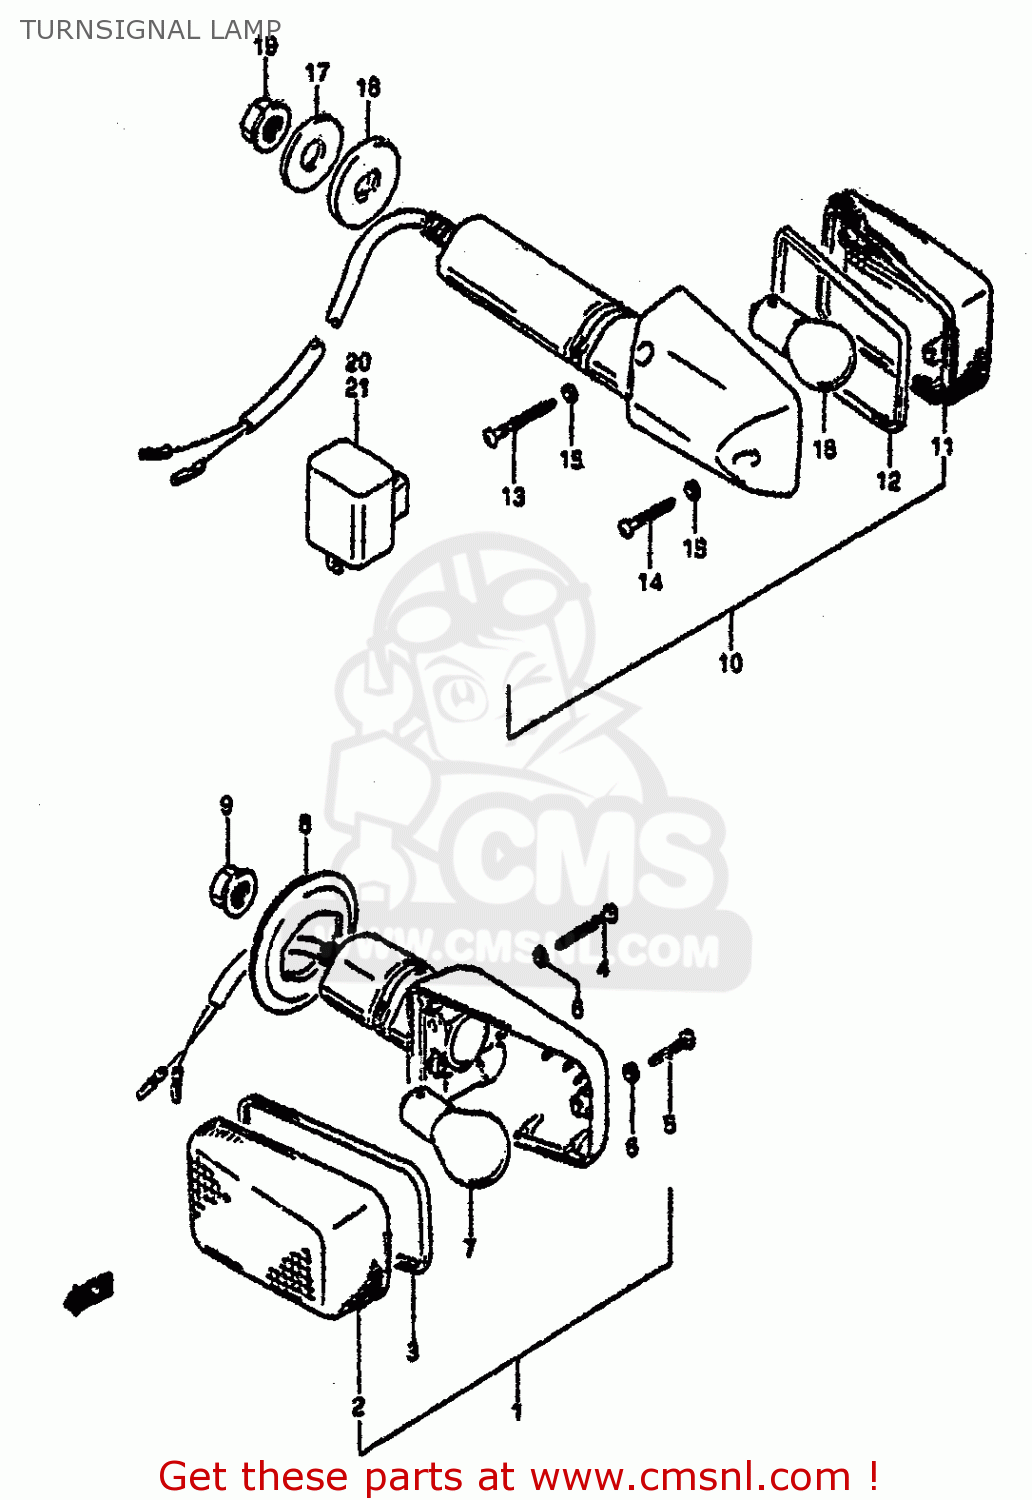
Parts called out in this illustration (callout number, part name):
1	LAMP ASSY,FR TURN SIGNAL
2	LENS
3	GASKET (NAS)
4	SCREW(3X30)
5	SCREW
6	GASKET (NAS)
7	BULB(12V21W)
8	GROMMET
9	NUT
10	LAMP ASSY,RR TURNSIGNAL
11	LENS
12	GASKET (NAS)
13	SCREW(3X30)
14	SCREW
15	GASKET (NAS)
16	BULB(12V21W)
17	WASHER(10.5X30X3.2)
18	SPACER,RR TURNSIGNAL
19	NUT
20	RELAY ASSEMBLY,TURN SIGNAL
21	RELAY ASSY,TUR
